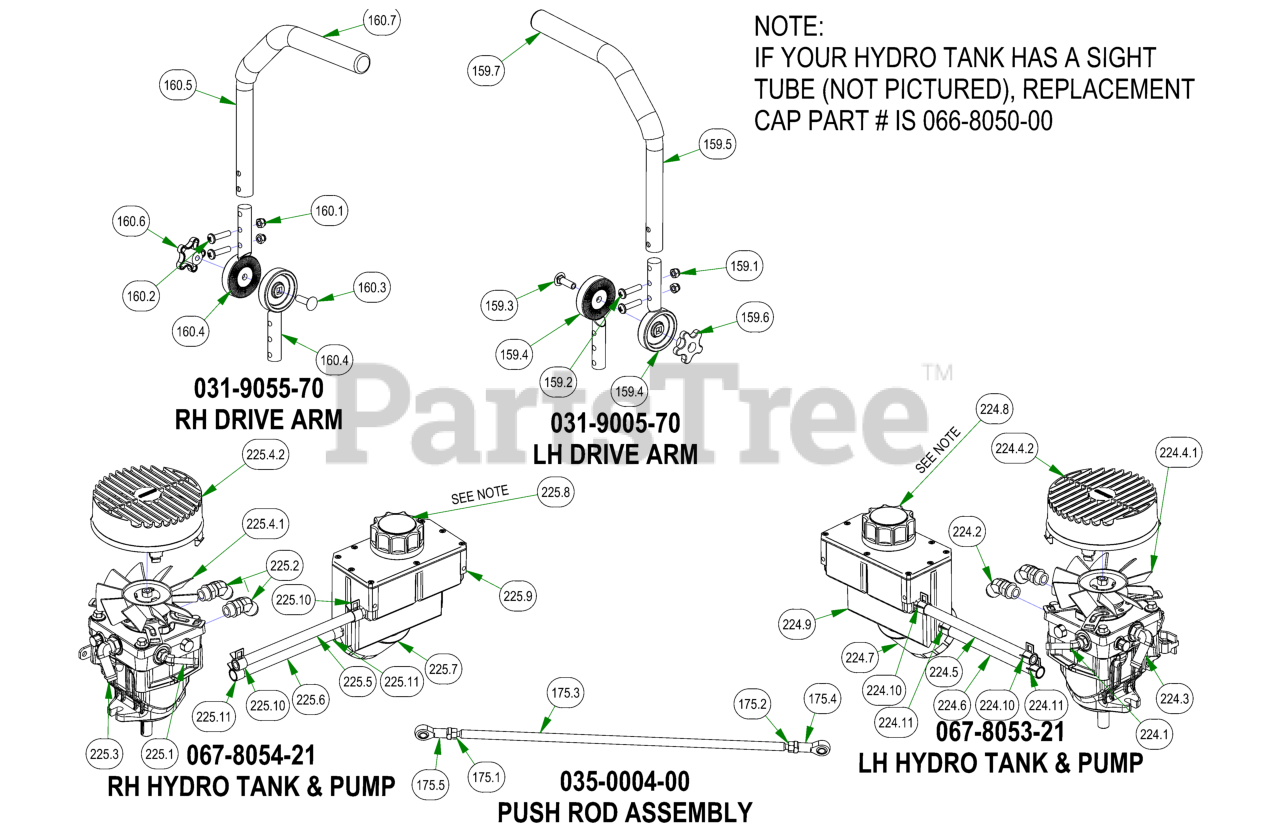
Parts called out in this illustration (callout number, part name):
159	2019 Left Hand ADJ. Steering Arm Kit
159.1	5/16-18 NYL INS L/N ZC
159.2	5/16-18 x 1 3/8" Futton Head Torx Drive Bolt
159.3	3/8-16 X 1-1/4 CARRIAGE BOLT ZINC
159.4	2019 Steering Arm Adjuster Casting
159.5	2019 Steering Arm Tube
159.6	Black Knob for Adjustable Steering Arm
159.7	Black Steering Arm Grip
160	2019 Right Hand ADJ. Steering Arm Kit
160.1	5/16-18 NYL INS L/N ZC
160.2	5/16-18 x 1 3/8" Futton Head Torx Drive Bolt
160.3	3/8-16 X 1-1/4 CARRIAGE BOLT ZINC
160.4	2019 Steering Arm Adjuster Casting
160.5	2019 Steering Arm Tube
160.6	Black Knob for Adjustable Steering Arm
160.7	Black Steering Arm Grip
175	2019 Outlaw Gen2 XP Push Rod Assembly
175.1	5/16" RH Fine Threaded Jam Nut
175.2	5/16" LH Fine Threaded Jam Nut
175.3	2019 Outlaw Gen2 Xp Rod
175.4	Spherical Rod End - Outlaw
175.5	Spherical Rod End - Outlaw
224	2021 LH ROGUE HYDRO TANK LINE ASSY
224.1	ZT Fitting, 3/8 x 3/8 45 Degree, 4603-6-6
224.2	2019 Outlaw 45 Degree Pump Fitting #6802-10-08
224.3	90 Degree Fitting, 1/2 x 3/4, 4601-8-8
224.4	2019 Rogue/Renegade Left Pump 16cc
224.4.1	Hydro Fan - Light/Pup/Outlaw XP
224.4.2	Fan Guard 6" - Fits Wheel
224.5	3/8" Clear Hose x 4 1/2"
224.6	1/2 Clear Braded Hose Priced/Foot x 9.5"
224.7	Hydraulic Filter
224.8	Hydraulic Tank Cap W/Dipstick
224.9	2019 Left Outlaw Gen2 Hydro Tank Suspension Only
224.10	3/8" Hose Clamp
224.11	1/2 Hose Clamp
225	2021 RH ROGUE HYDRO TANK LINE ASSY
225.1	ZT Fitting, 3/8 x 3/8 45 Degree, 4603-6-6
225.2	2019 Outlaw 45 Degree Pump Fitting #6802-10-08
225.3	90 Degree Fitting, 1/2 x 3/4, 4601-8-8
225.4	2019 Rogue Right Pump 16cc
225.4.1	Hydro Fan - Light/Pup/Outlaw XP
225.4.2	Fan Guard 6" - Fits Wheel
225.5	3/8" Clear Hose x 4 1/2"
225.6	1/2 Clear Braded Hose Priced/Foot x 9.5"
225.7	Hydraulic Filter
225.8	Hydraulic Tank Cap W/Dipstick
225.9	2019 Right Outlaw Gen2 Hydro Tank Suspension Only
225.10	3/8" Hose Clamp
225.11	1/2 Hose Clamp
